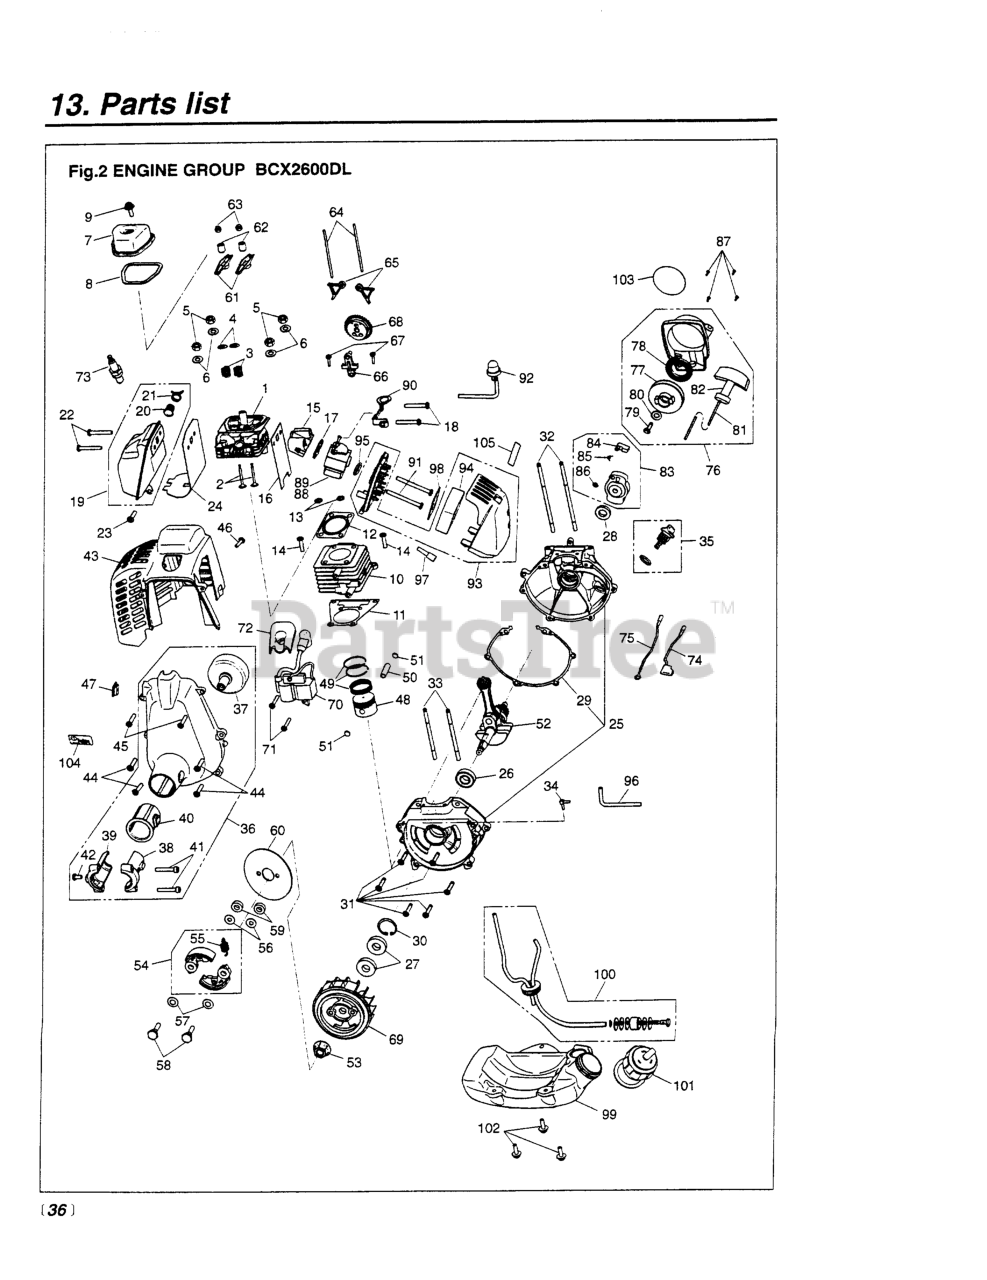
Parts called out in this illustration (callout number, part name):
3	SPRING VALVE
4	RETAINER
37	DRUM, CLUTCH (USE 182298)
40	CUSHION
42	BOLT (USE 3310-31720)
43	COVER, ENGINE (USE 182288)
55	SPRING
56	WASHER, FLAT (USE 182303)
58	SCREW (USE 182305)
59	SPACER (USE 182297)
74	CORD (A)
75	CORD (B)
80	WASHER (USE 181741)
98	NET, CLEANER (USE 182294)
